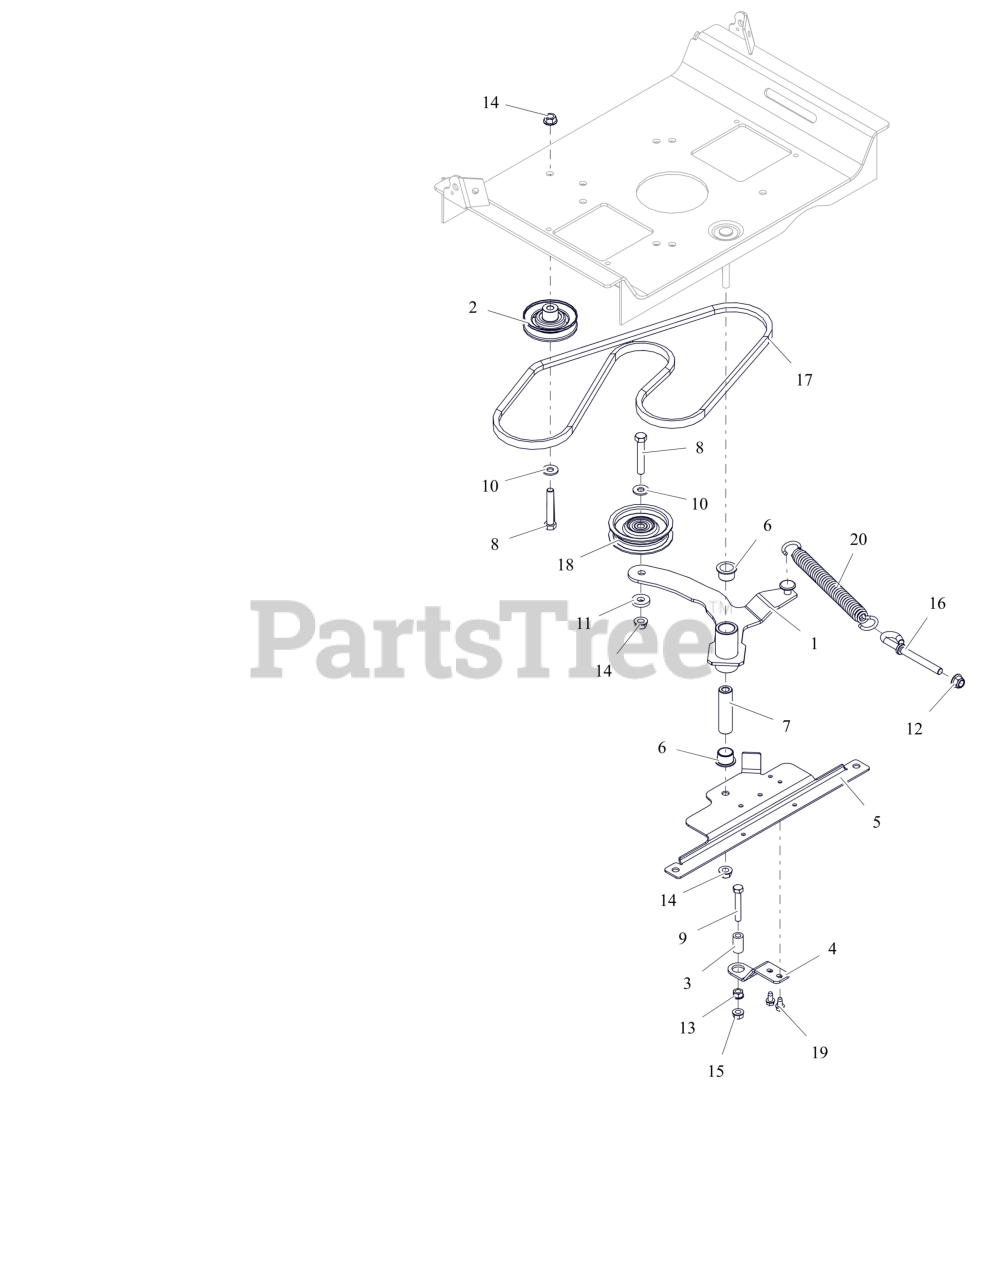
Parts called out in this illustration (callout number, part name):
1	WLDMT,GRD DRIVE IDLER ARM-LGR
2	IDLER, V-3.000 OD
3	SPACER, RUBBER 5/16 IDX1.0 LG
4	BRKT, CLUTCH STOP (XL)
5	BRKT, IDLER ATTACHMENT (BLACK)
6	BSHG-FLG 0.75X0.875X.625X1.125
7	BUSHING, SLEEVE .38X.750X2.78
8	BLT,HEX .38-16X2.25 G5 ZCC
9	BLT, HEX .31-18X2.00 G5 ZCC
10	WSHR,FLT .375X.875X.083 ZCC
11	WSHR, FLT .406X1.00X.188 ZCC
12	NUT,NYL-FLG .38-16 GF ZCC
13	NUT,SPNLK-FLG .31-18 G5 ZCC
14	NUT-LK-TOP-FLG .38-16 ZC120
15	NUT-LK-TOP-FLG .312-18 GF ZCC
16	BOLT, EYE - 38-16 UNC 2-A
17	V-BELT, A-RAW EDGE
18	SHEAVE, IDLER -V .38 x 4.00
19	SCR-TAP .25-20X.50 HWH ZCC
20	SPRING- EXTENSION
